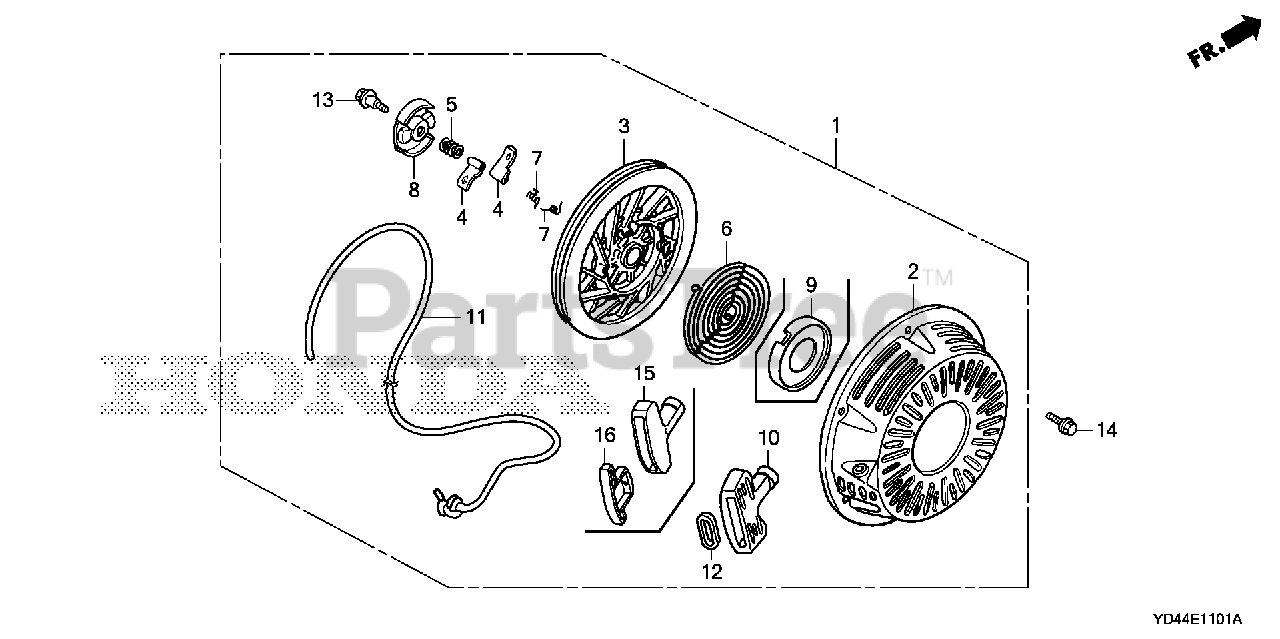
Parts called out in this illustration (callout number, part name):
1	STARTER ASSY., RECOIL *R280* (POWER RED)
2	CASE, RECOIL STARTER *R280* (POWER RED)
3	PULLEY, RECOIL STARTER
4	RATCHET, STARTER
5	SPRING, FRICTION
6	SPRING, STARTER RETURN
7	SPRING, RATCHET
8	RETAINER, SPRING
9	HOLDER, SPRING (NOT AVAILABLE)
10	GRIP, STARTER
11	ROPE, RECOIL STARTER
12	REINFORCEMENT, GRIP
13	SCREW, CENTER
14	BOLT, FLANGE (6X10)
